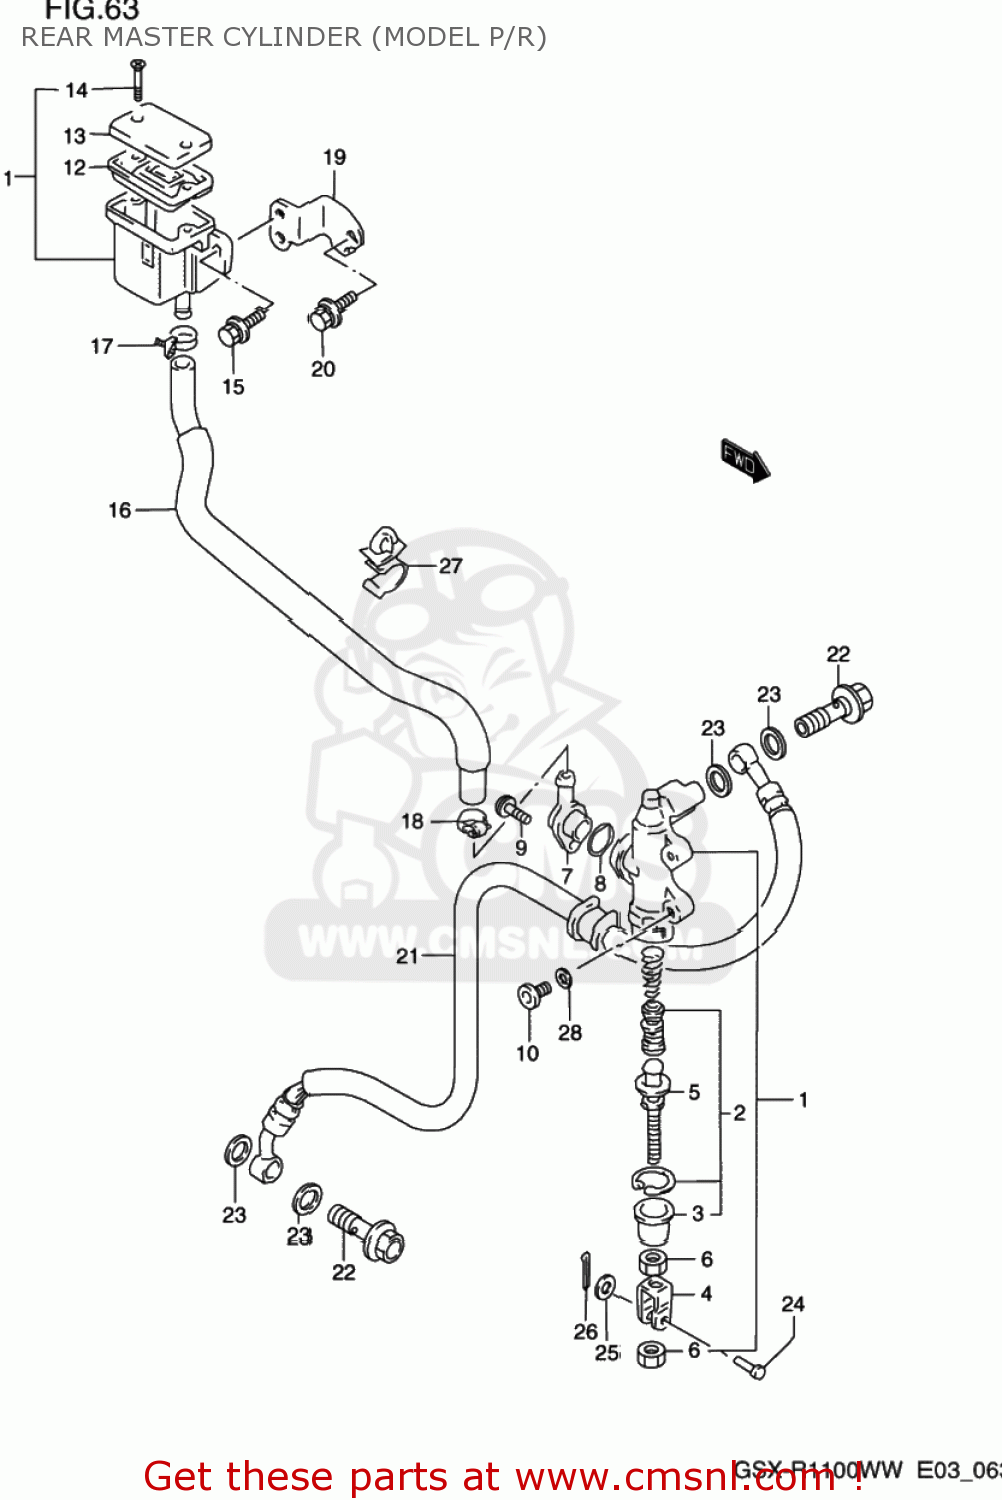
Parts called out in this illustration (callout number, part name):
1	CYLINDER ASSEMBLY,REAR MASTER
2	PISTON/CUP SET
3	BOOT
4	YOKE
5	ROD,PUSH
6	NUT
7	CONNECTOR
8	O RING
9	SCREW
10	SCREW(8X22)
11	TANK ASSY,RESERVOIR
12	DIAPHRAGM
13	CAP
14	SCREW
15	BOLT
16	HOSE,RESERVOIR TANK
17	CLAMP
18	CLAMP
19	PLATE,RESERVOIR TANK
20	BOLT
21	HOSE COMP,REAR BRAKE
22	BOLT UNION
23	WASHER(10X15X1.5)
24	PIN
25	WASHER
26	PIN
27	CLAMP
28	LOCK WASHER
